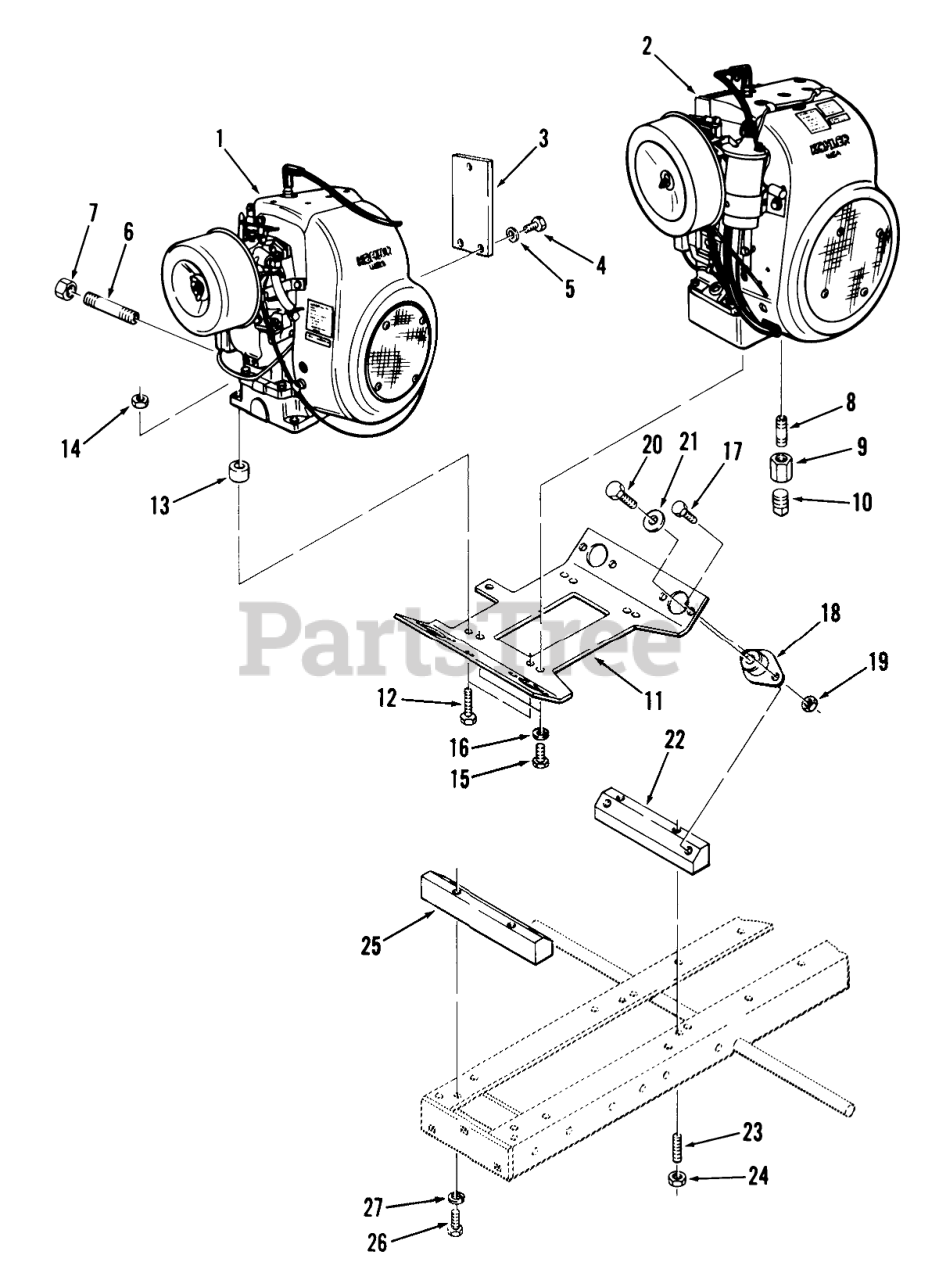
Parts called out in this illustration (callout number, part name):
1	Engine-8HP Kohler K-181S Spec Pf-30700D
2	Engine-12HP Kohler K-301AS Spec Pf-47648D
2	Engine-10HP KohlerK-241AS Spec Pf-46766D
8	Pipe Nipple 1/4 X 7/8 C-161, C-141, C-121, C-101 Only
13	SPACER
